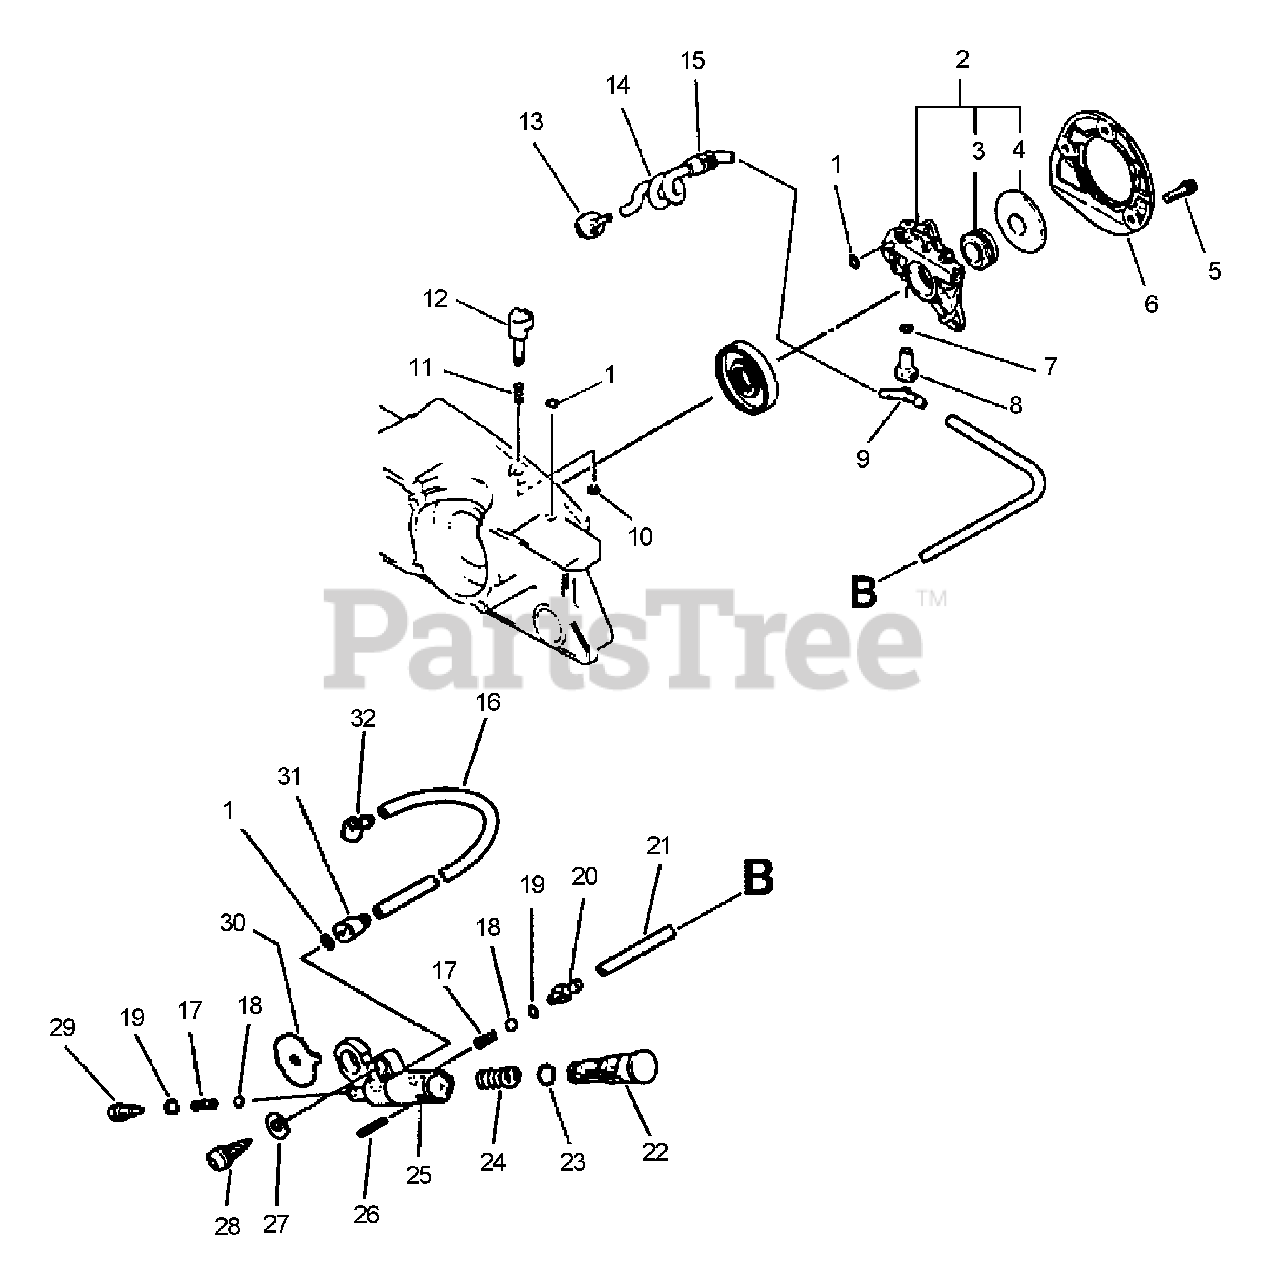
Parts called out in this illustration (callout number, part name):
1	O-RING - 3
2	AUTO-OILER ASSY
3	GEAR - WORM
4	WASHER - 12
5	SCREW - 4X12
6	COVER, OIL PUMP
7	CLIP - 6.5
8	CONNECTOR, PIPE
9	PIPE - 3X6X20 -- BLACK
10	RING, RETAINING - 3
12	DIAL, AUTO-OILER
13	FILTER, OIL
14	PIPE - OIL
16	PIPE, OIL - 3X6X125
17	SPRING, VALVE
18	VALVE, BALL
21	PIPE - OIL
22	PISTON, OIL PUMP
23	O-RING - 7
25	BODY, OIL PUMP
26	PIN - SPRING -- 2X16
27	WASHER - 5
28	SCREW - 5X20
29	ADAPTER, OIL PUMP
30	BRACKET, OIL PUMP
31	CONNECTOR, PIPE
32	CONNECTOR, PIPE
